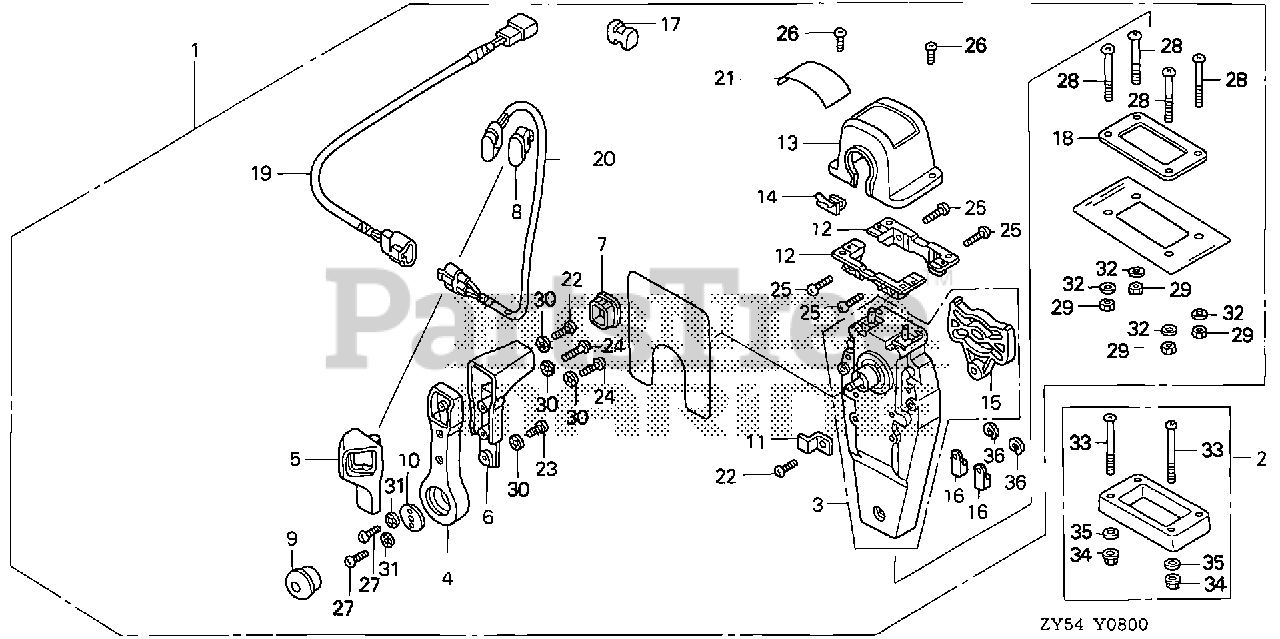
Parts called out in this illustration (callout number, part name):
1	BOX KIT, REMOTE CONTROL (TOP MOUNT SINGLE)(R)
1	BOX KIT, R. REMOTE CONTROL (TOP MOUNT SINGLE)
2	SPACER KIT, REMOTE CONTROL BOX (TOP MOUNT SINGLE)
3	HOUSING ASSY., L. (INNER) (TOP MOUNT)
4	HANDLE, REMOTE CONTROL
5	COVER, L. GRIP
6	GRIP, REMOTE CONTROL HANDLE
7	CAP, GRIP
8	CAP, SWITCH
9	BUTTON, THROTTLE
10	PLATE, HANDLE
11	PLATE, CABLE CLAMP
12	BRACKET, REMOTE CONTROL HOUSING
13	HOUSING, REMOTE CONTROL BOX
14	HOUSING, LEAD
15	PLATE, DWELL
16	TERMINAL, CABLE
17	SPACER, CABLE CLAMP
18	GASKET, SINGLE
19	SUB-HARNESS ASSY., POWER TRIM-TILT (A)
20	SWITCH ASSY., POWER TRIM-TILT (A)
21	MARK, REMOTE CONTROL (SINGLE)
22	SCREW, PAN (5X16)
23	SCREW, PAN (5X10)
24	SCREW, PAN (5X20)
25	SCREW, PAN (5X18)
26	SCREW, PAN (4X10)
27	SCREW, PAN (6X18)
28	SCREW, PAN (5X40)
29	NUT, HEX. (5MM)
30	WASHER, LOCK (5MM)
31	WASHER, LOCK (6MM)
32	WASHER, PLAIN (5MM)
33	SCREW, PAN (5X65)
34	NUT, HEX. (5MM)
35	WASHER, PLAIN (5MM)
36	E-RING (6MM)
